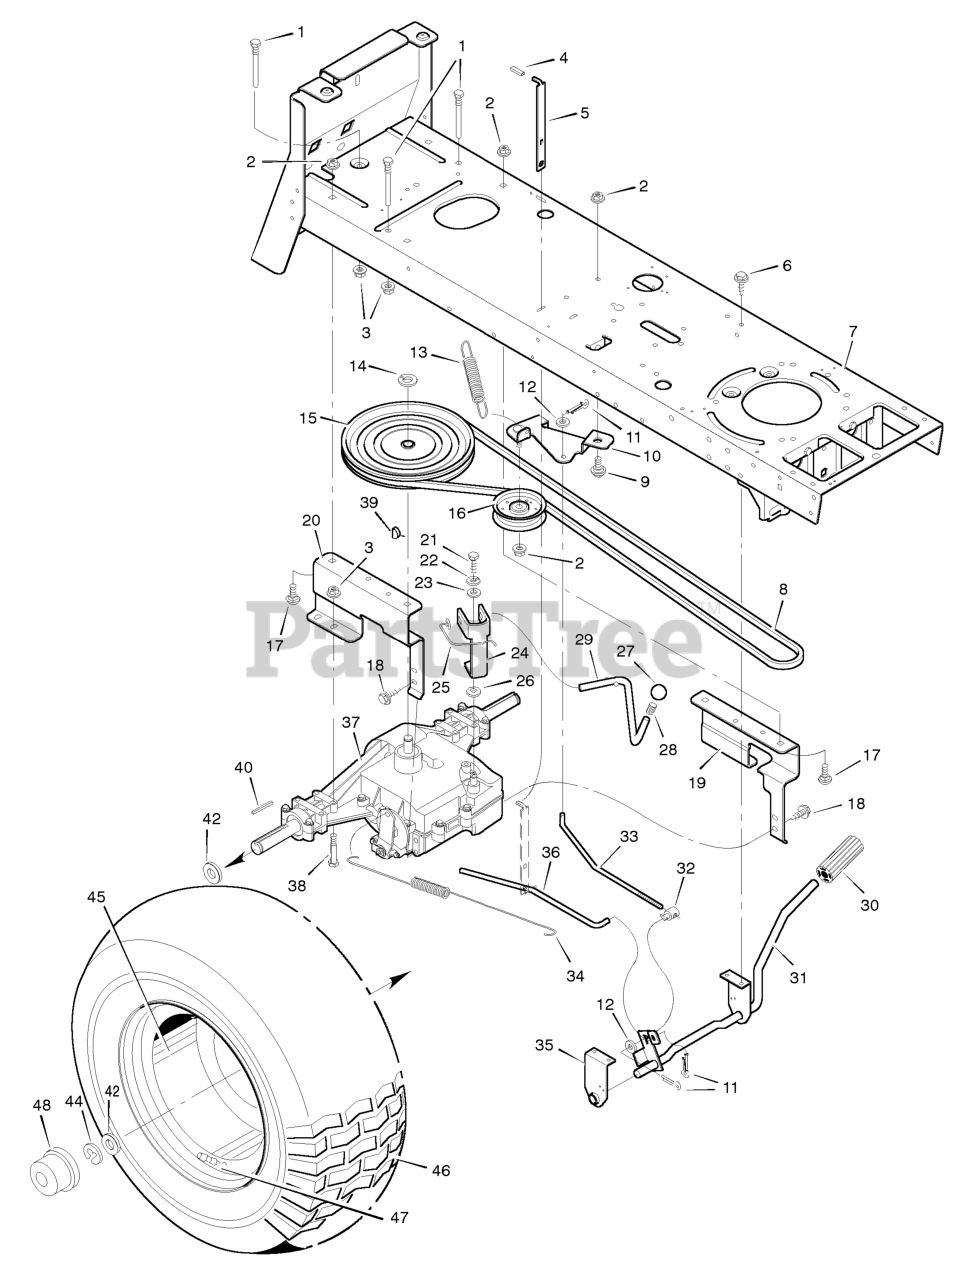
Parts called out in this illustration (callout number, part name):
1	Guide, Belt
2	Locknut, Flange
3	Locknut, Flange
5	Lever, Parking Brake
8	Belt, Motion Drive
9	Bolt, Shoulder
10	Bracket Assembly, Idler
11	Pin, Cotter
12	Washer
13	Spring, Drive Extension
14	Ring, Retainer
15	Pulley, Motion Drive
16	Pulley, Backside Idler
17	Bolt, Carriage
19	Bracket, Left Transaxle
20	Bracket, Right Transaxle
21	Bolt, Hex
22	Lockwasher
24	Yoke, Shift Lever
25	Spring
27	Knob, Shift Lever
28	Ring, Tolerance
29	Lever, Shift
30	Pedal, Clutch/Brake
31	Lever Assembly, Pedal
32	Nut, Adjustable
33	Rod, Clutch
34	Spring, Brake Extension
35	Bracket, Pedal Support
36	Rod, Brake Latch
37	Transaxle, Peerless **
38	Bolt, Hex
39	Key, Woodruff No. 9
40	Key, Square
45	Wheel & Tire Assembly
46	Tire Only *
47	Valve Stem
48	Cap, Hub
